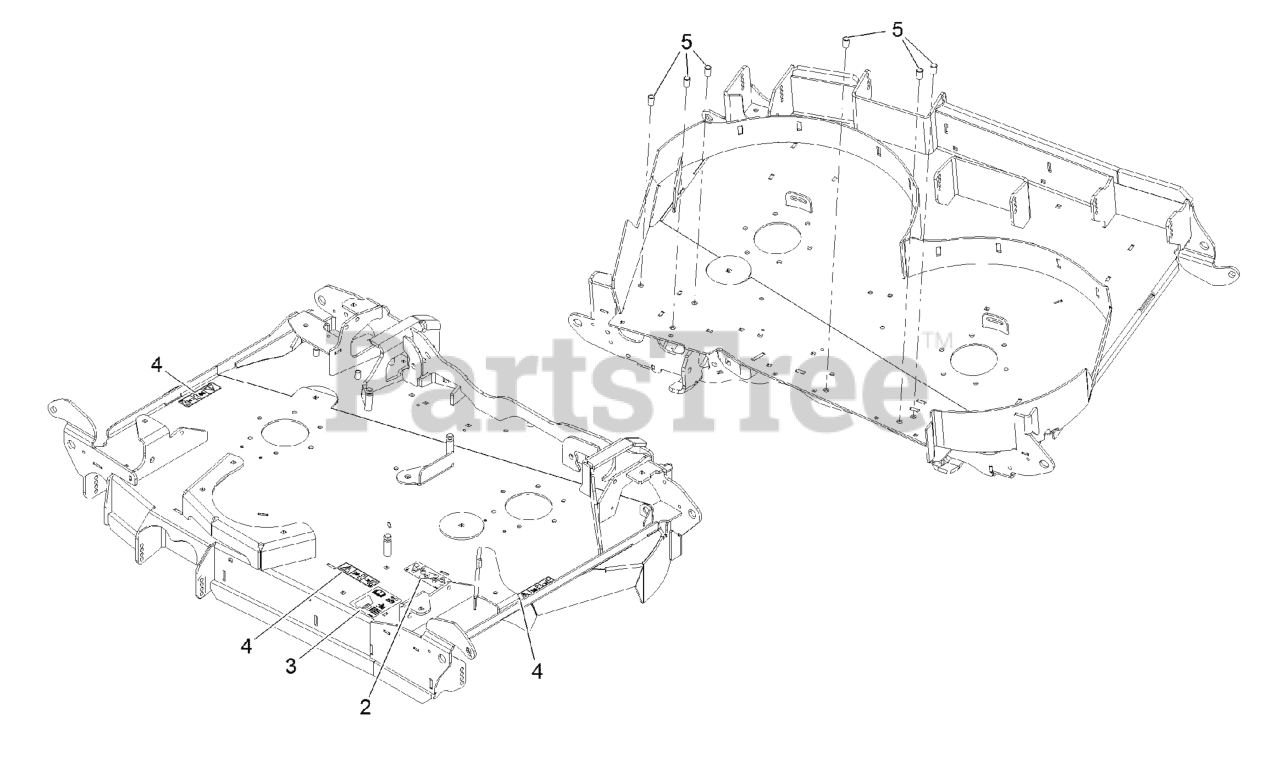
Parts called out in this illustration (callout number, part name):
2	DECAL-ROUTING, BELT
3	DECAL-ROLLER, ANTI-SCALP
4	DECAL-COVER, MISSING
5	NUT-CLINCH
